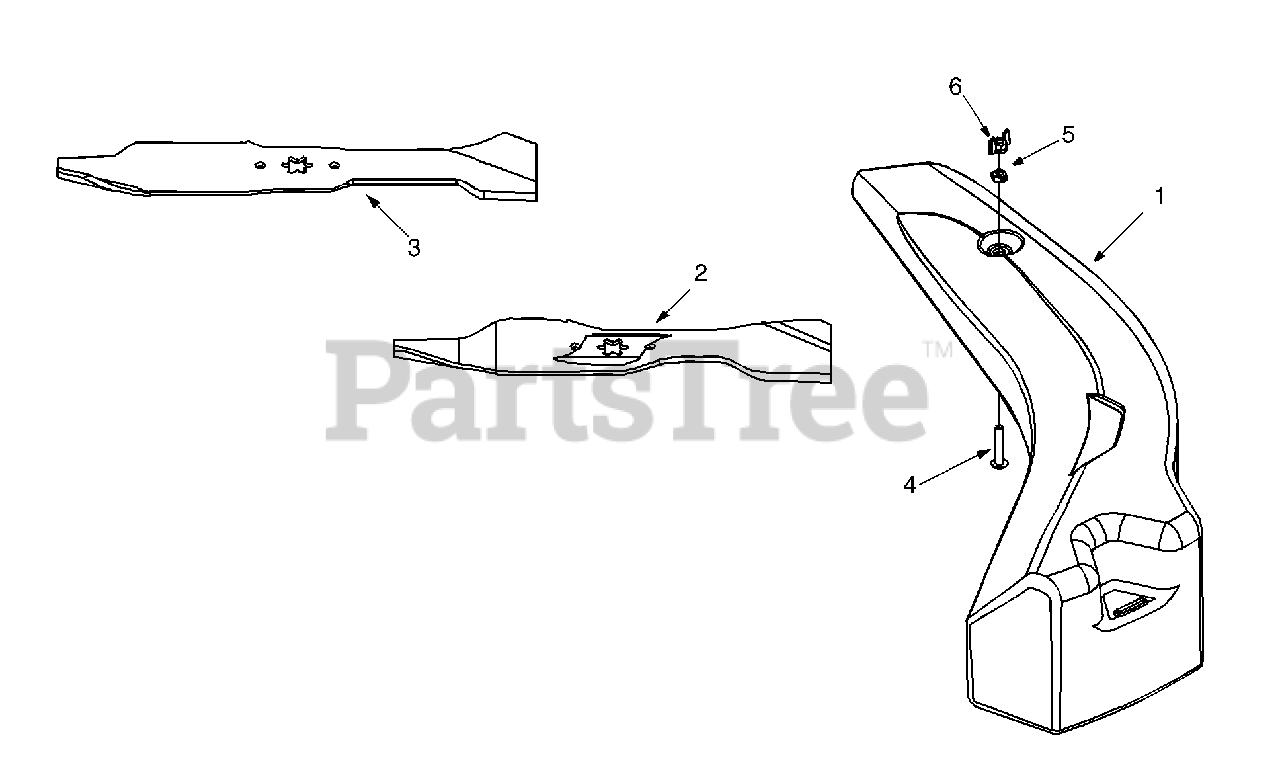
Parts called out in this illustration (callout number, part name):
1	Mulch Plug
2	Mulching Blade: 14.88" Lg.
3	Mulching Blade: 16.28" Lg.
4	Machine Screw 1/4"
5	Lock Nut 1/4" Thd.
6	Wing Nut
